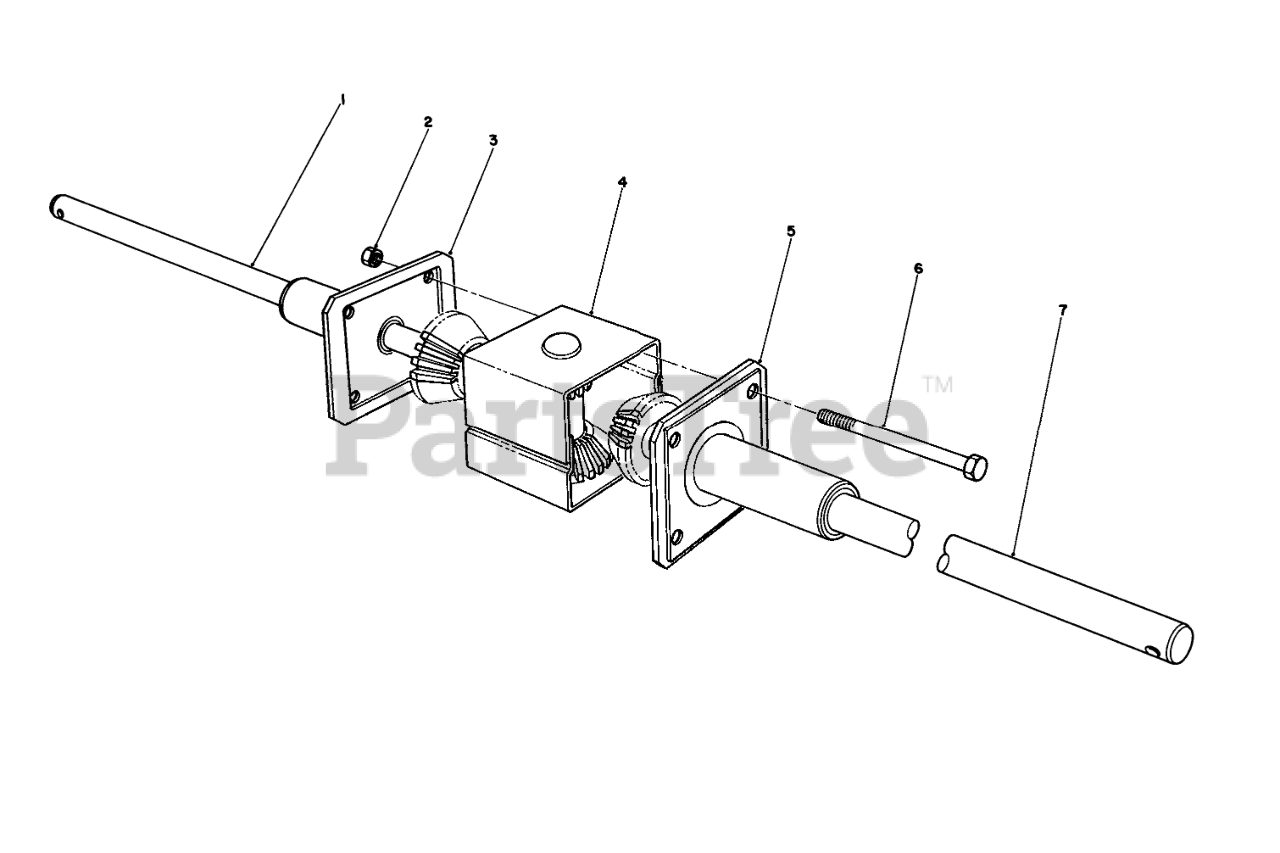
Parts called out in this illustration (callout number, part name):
2	NUT-LOCK, CONE
3	END CAP/BRG ASM
4	GEAR CASE ASM
5	END CAP &BEARING ASY
6	SCREW-HH
